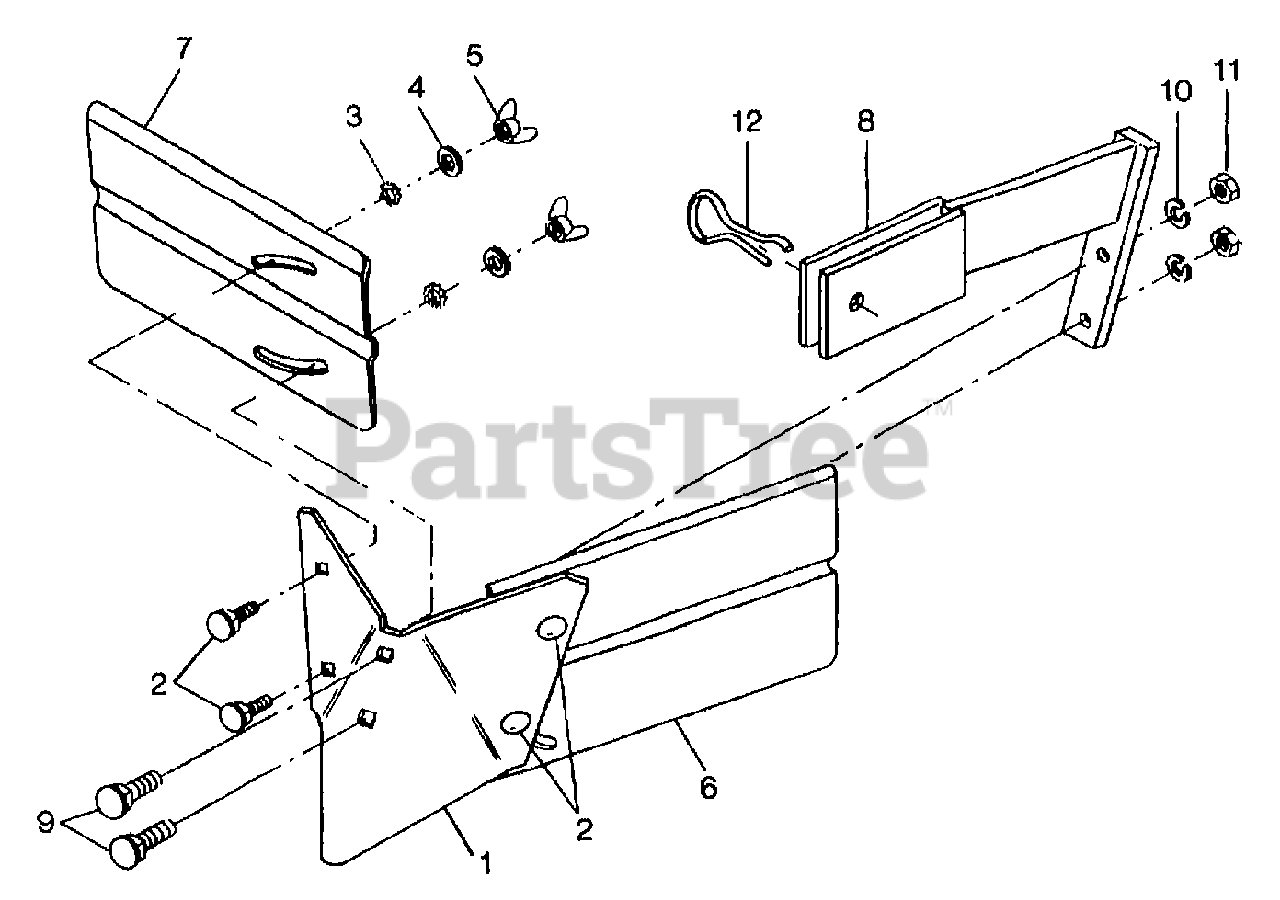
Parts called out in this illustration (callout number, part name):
1	BLADE-HILLER/FURROWER
2	SCR-CARR 5/16-18X.75 G2 ZP
3	WASHER-LK .312 EXT TOOTH
4	WASHER-FLAT 5/16 SAE
5	NUT-WING/LK 5/16-18 ZP
6	WING-HILLER/FURROWER LH
7	WING-HILLER/FURROWER RH
8	BRKT-HILLER/FURROWER
9	BOLT-CARR 3/8-16X1.5 ZP
10	WASHER-LK .375 @ DEPL
11	NUT-HEX 3/8-16 ZP
12	PIN-CLINCH .312DIA ZP
